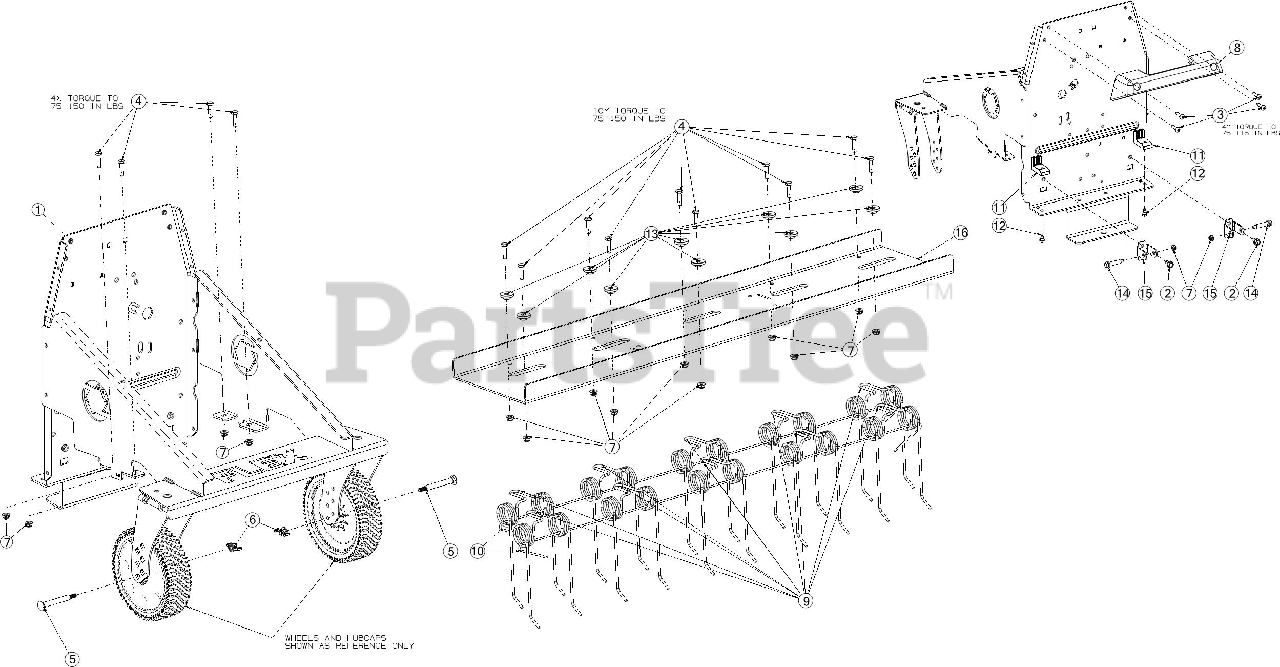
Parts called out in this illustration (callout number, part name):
1	DETHATCHER FRAME ASSEMBLY
2	SCREW 5/16-18 x .750
3	SCREW 1/4-20 x 1.0
4	SCREW 1/4-20 X1.00 GR5
5	CASTER AXLE
7	FLANGE LOCK NUT
9	DETHATCHER SPRING
10	DETHATCHER RETAINING WIRE
11	BUMPER PAD
12	SHOULDER SCREW 1/4-20 x .50
13	SHOULDER SPACER
14	SHOULDER SCREW
15	SUPPORT BRACKET
16	DETHATCHER TRAY BRACKET
